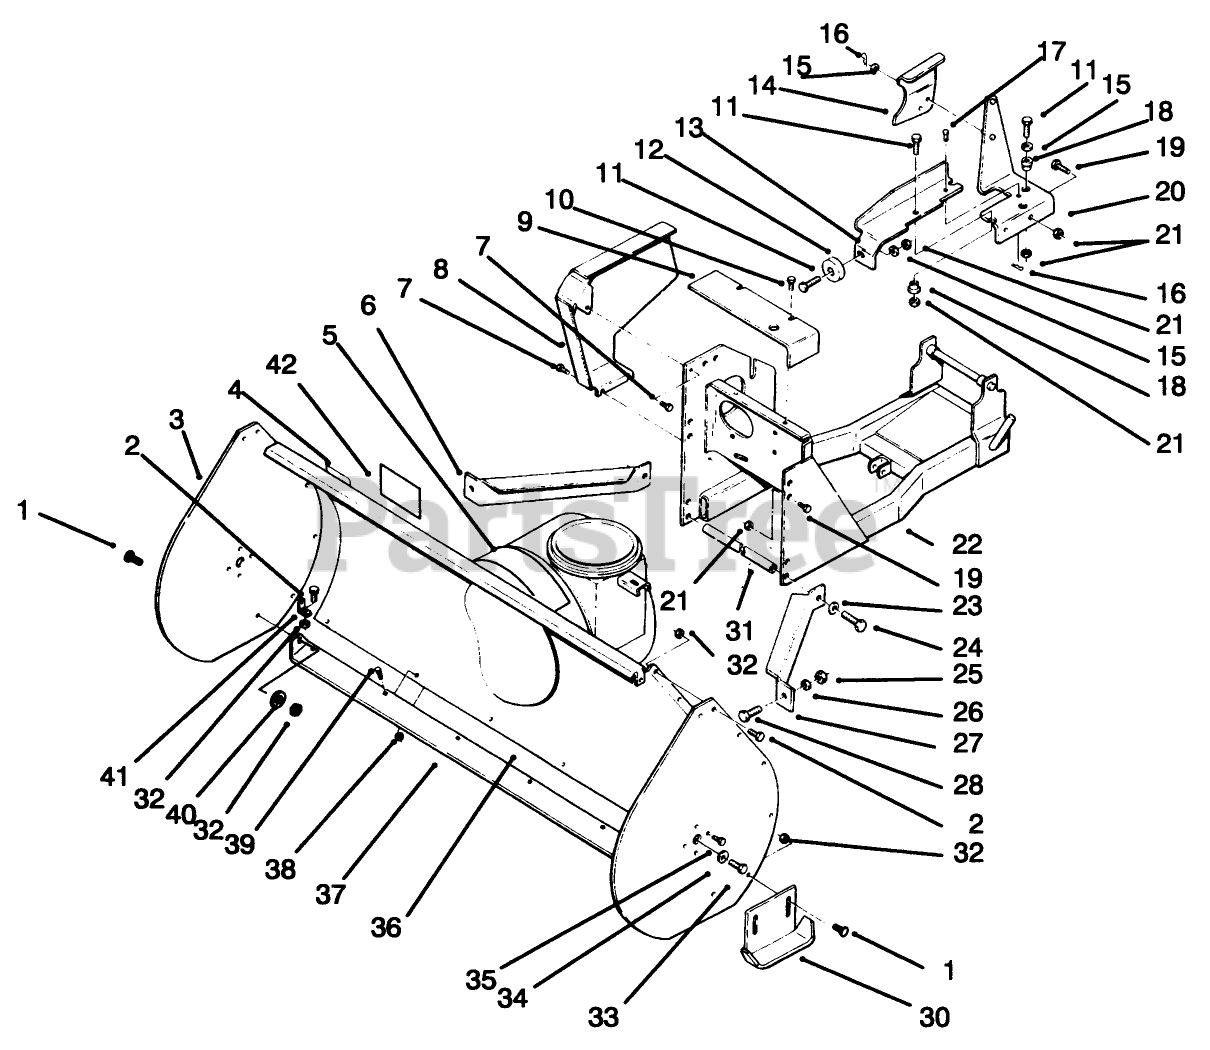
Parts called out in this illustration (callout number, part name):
1	BOLT-CARR
2	SCREW-HH
7	Bolt
9	GUARD *R
11	SCREW-HH
15	WASHER-FLAT
16	Hairpin
18	SPACER-LIFT LINK
19	SCREW-HH
21	NUT-LOCK, NI
23	WASHER-LOCK
24	SCREW-HH
26	WASHER-FLAT
28	SCREW-CARR
32	NUT-LOCK, NI
33	SCREW-HH, LOCK
34	WASHER
35	SCREW-HH
36	AUGER HSG/DECAL ASM
38	NUT-LOCK, NI
40	WASHER-PLAIN
42	DECAL-WARNING
